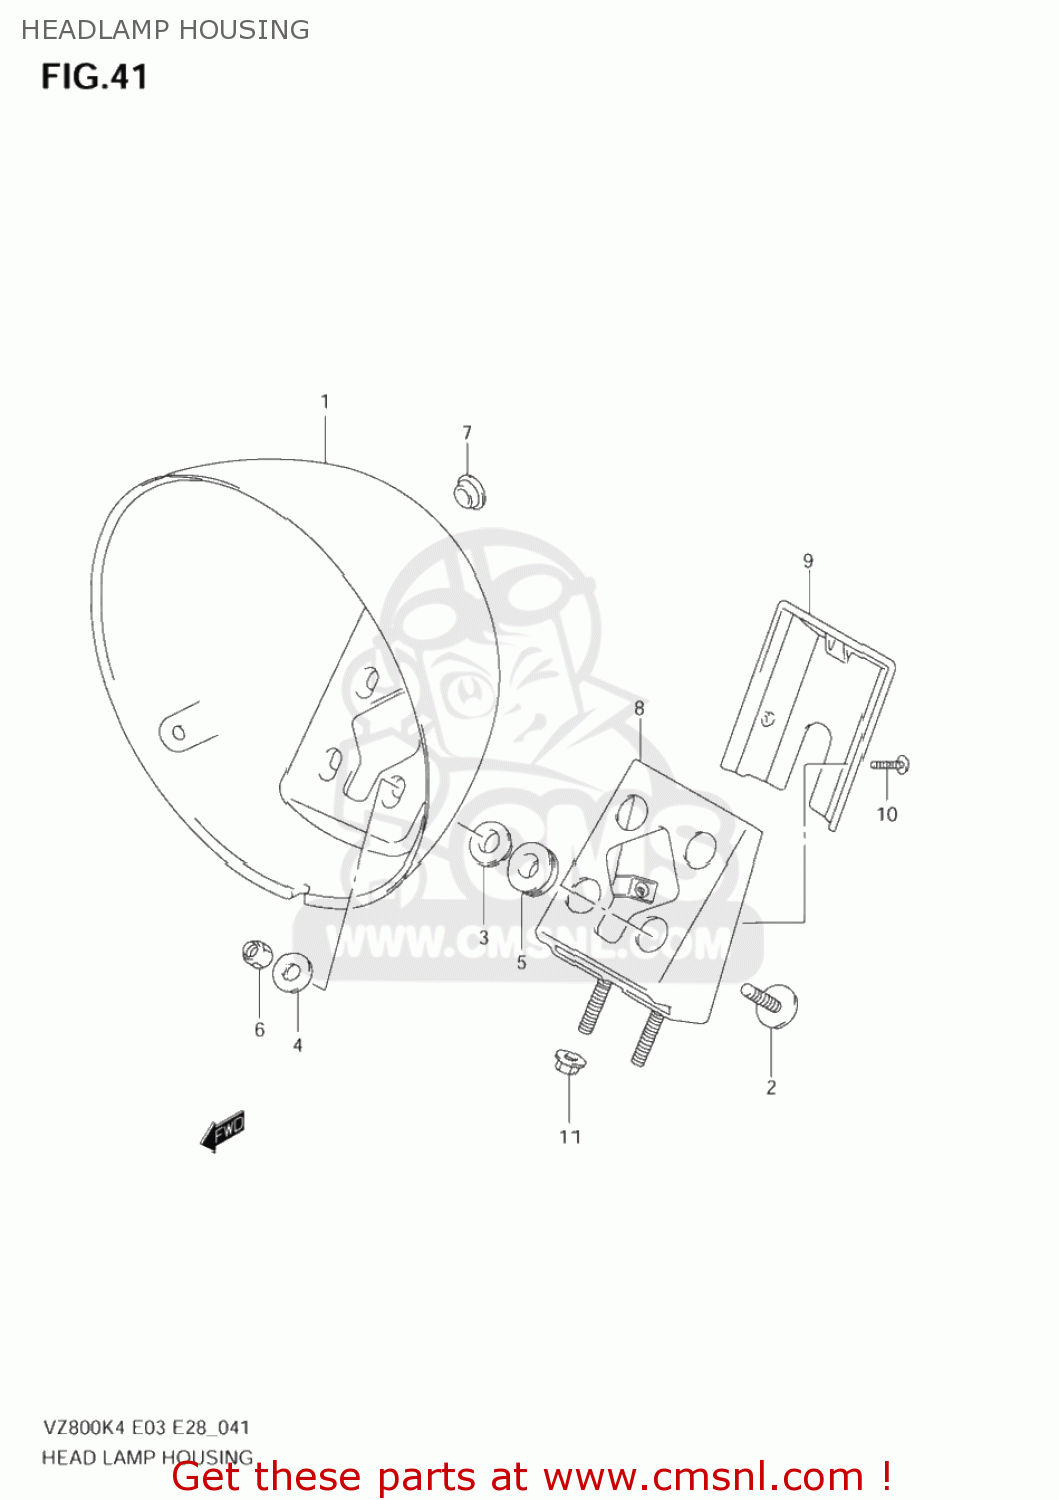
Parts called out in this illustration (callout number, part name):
1	HOUSING,HEADLAMP
2	BOLT(6X25)
3	WASHER
4	WASHER(6.5X22X2.3)
5	CUSHION
6	NUT
7	CAP,HEADLAMP HOUSING
8	BRACKET,HEADLAMP HOUSING
9	COVER,HEADLAMP HSG BRACKET
10	SCREW
11	NUT
